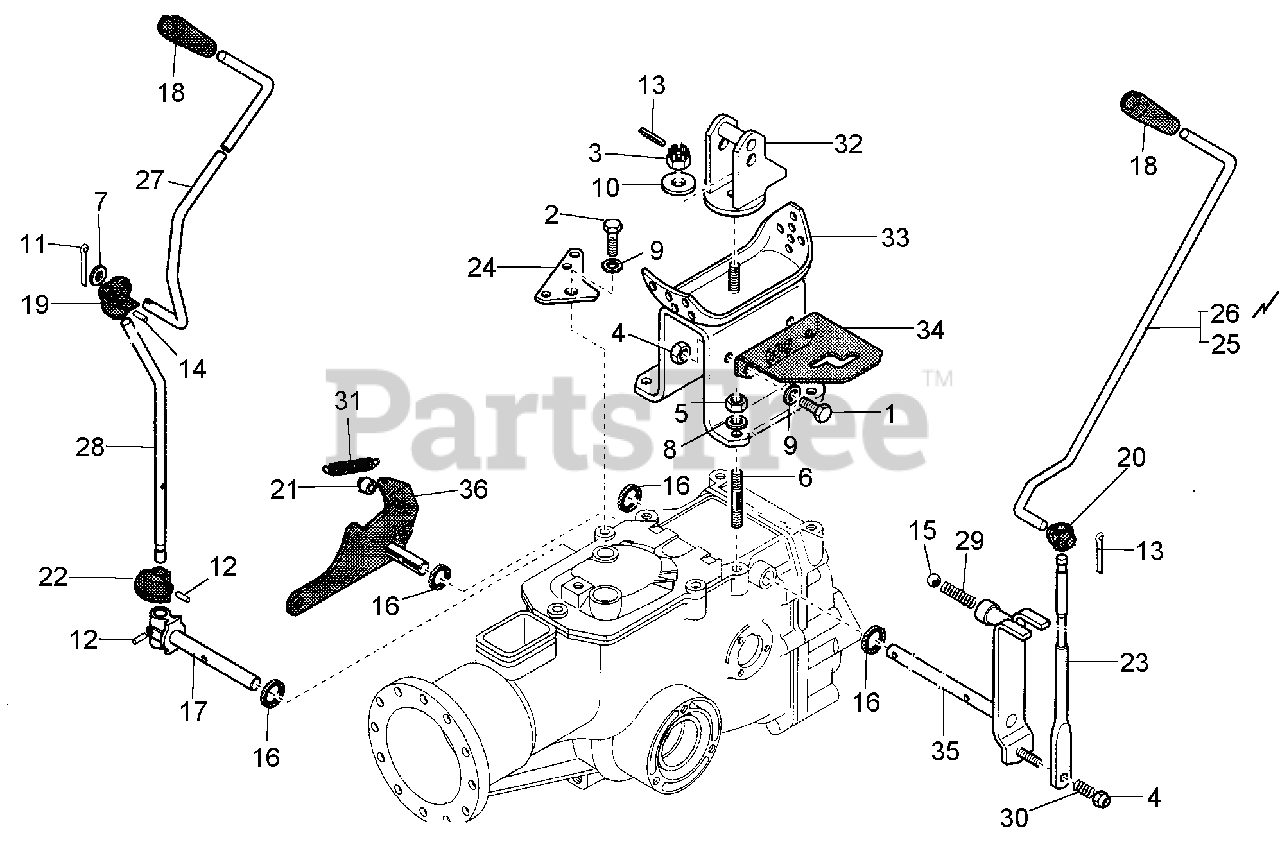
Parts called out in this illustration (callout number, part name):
1	SCREW, M8X20
2	SCREW, M8X30
3	NUT, CASTLE, M12
4	NUT, SELF LOCKING, M8
6	STUD, M8X38X14X20
7	WASHER, M10.5
8	SUPER WASHER
9	WASHER, LOCK, M8.4
10	LOCK WASHER, M13
12	PIN, LOCKING, M4X20
13	PIN, LOCKING, M3X22
14	PIN, LOCKING, M4X24
15	BALL, 15/32"
16	OIL SEAL, 14X22X4
19	PTO ARTICULATION
20	SPEED ARTICULATION, 716, 720, 730
21	PTO LOCKOUT RING
22	PTO STOP RING
23	SPEED CONTROL LEVER
24	REVERSE BRACKET
25	SPEED CONTROL ROD, RECOIL START
26	SPEED CONTROL ROD, ELECTRIC START
27	PTO CONTROL ROD, ELECTRIC START
28	PTO CONTROL LEVER
32	HANDLE BAR SUPPORT
33	HANDLE BAR ANCHOR
34	GEAR SELECTOR, 716, 720, 730
35	SPEED CONTROL LEVER, 716, 720, 730
36	REVERSE LEVER
